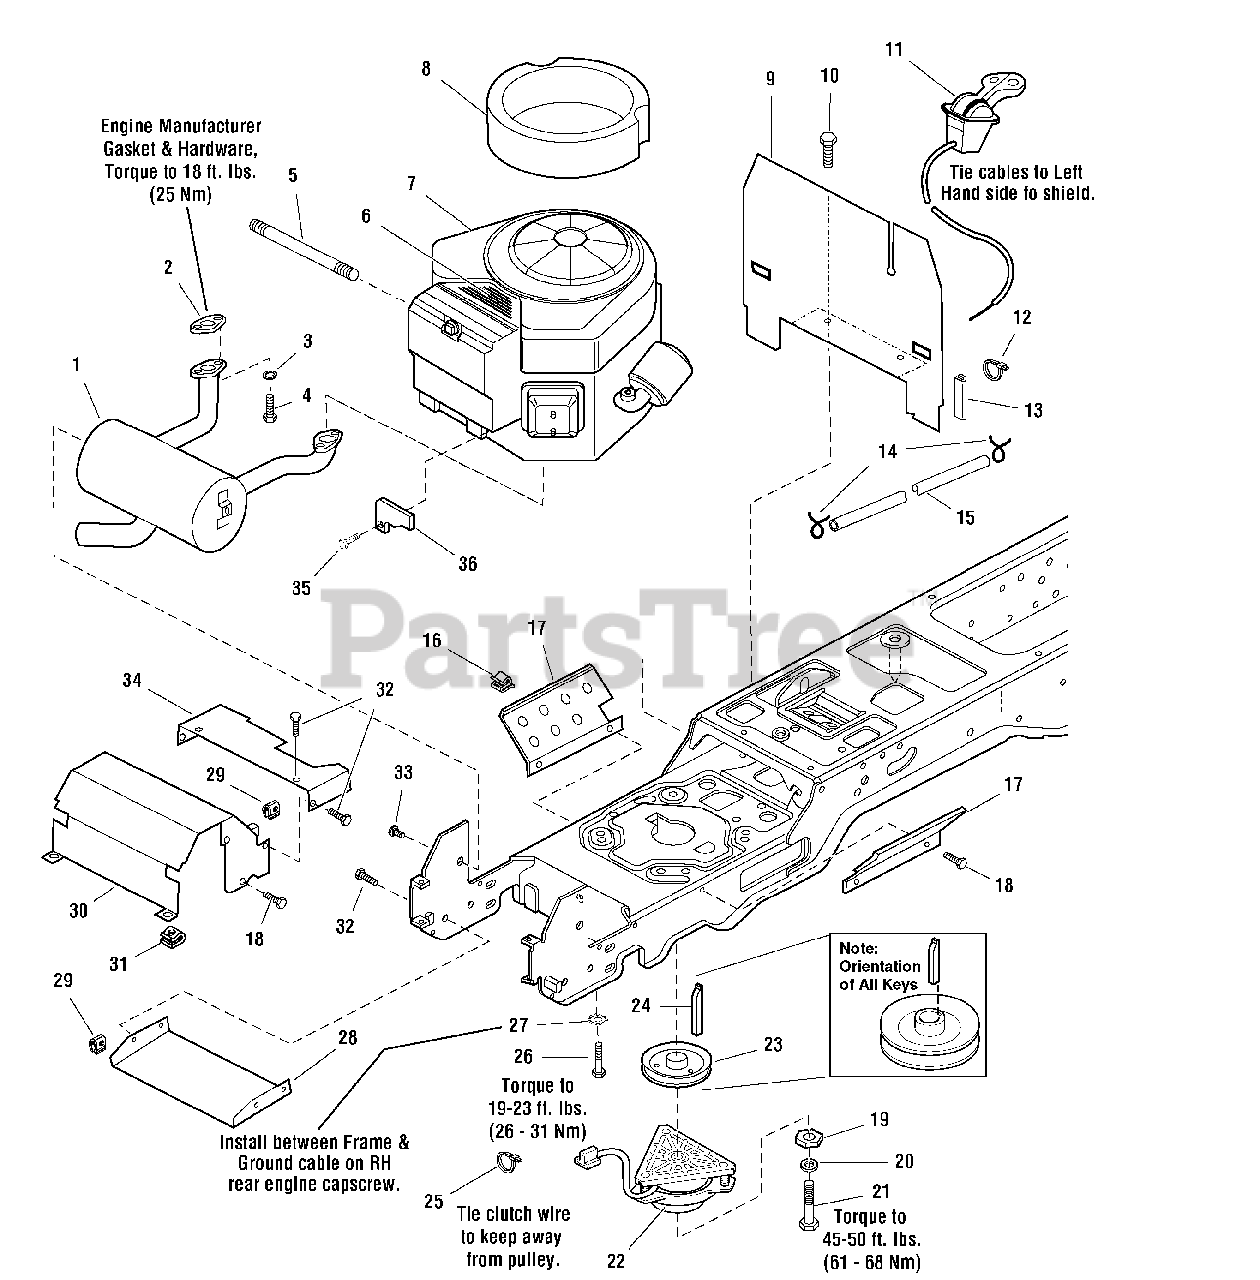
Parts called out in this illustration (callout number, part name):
1	MUFFLER
2	* GASKET
3	LOCKWASHER, 5/16
4	CAPSCREW, Socket Head, 5/16-18 x 7/8, G8
5	HOSE, Oil Drain
6	* DECAL, 20HP
7	* ENGINE, 20 HP Briggs & Stratton INTEK Twin, Model 406777, Ty
8	SEAL, Circle
9	BULKHEAD
10	CAPSCREW, Hex Head Taptite, 1/4-20 x 1/2
11	CONTROL, Throttle Double 39" Long w/Knobs
12	TIE
13	EDGING, Rubber
14	CLAMP, Hose Type E
15	HOSE, 58" Long
16	CLIP, Wire
17	SHIELD
18	SCREW, Hex Head Taptite, 1/4-20 x 3/8
19	WASHER, Hex
20	LOCKWASHER, 7/16
21	CAPSCREW, Hex Head, 7/16-20 x 2-3/4
22	CLUTCH, Electric, OGURA
23	PULLEY & HUB ASSEMBLY, 4-1/2 OD
24	KEY
25	TIE
26	CAPSCREW, Hex Head Taptite, 3/8-16 x 1-1/2
27	LOCKWASHER, External Tooth, 3/8
28	SHIELD, Muffler Bottom
29	NUT, Speed,1/4-20
30	DUCT, Muffler Top
31	NUT, Speed, 5/16-18
32	CAPSCREW, Hex Head Flange Lock1/4-20 x 5/8
33	CAPSCREW, Hex Head Taptite, 5/16-18 x 1/2
34	DUCT, Muffler Extension
35	SCREW, Trox Head Taptite, 1/4-20 x 1/2
36	PLATE, Limiter RPM
